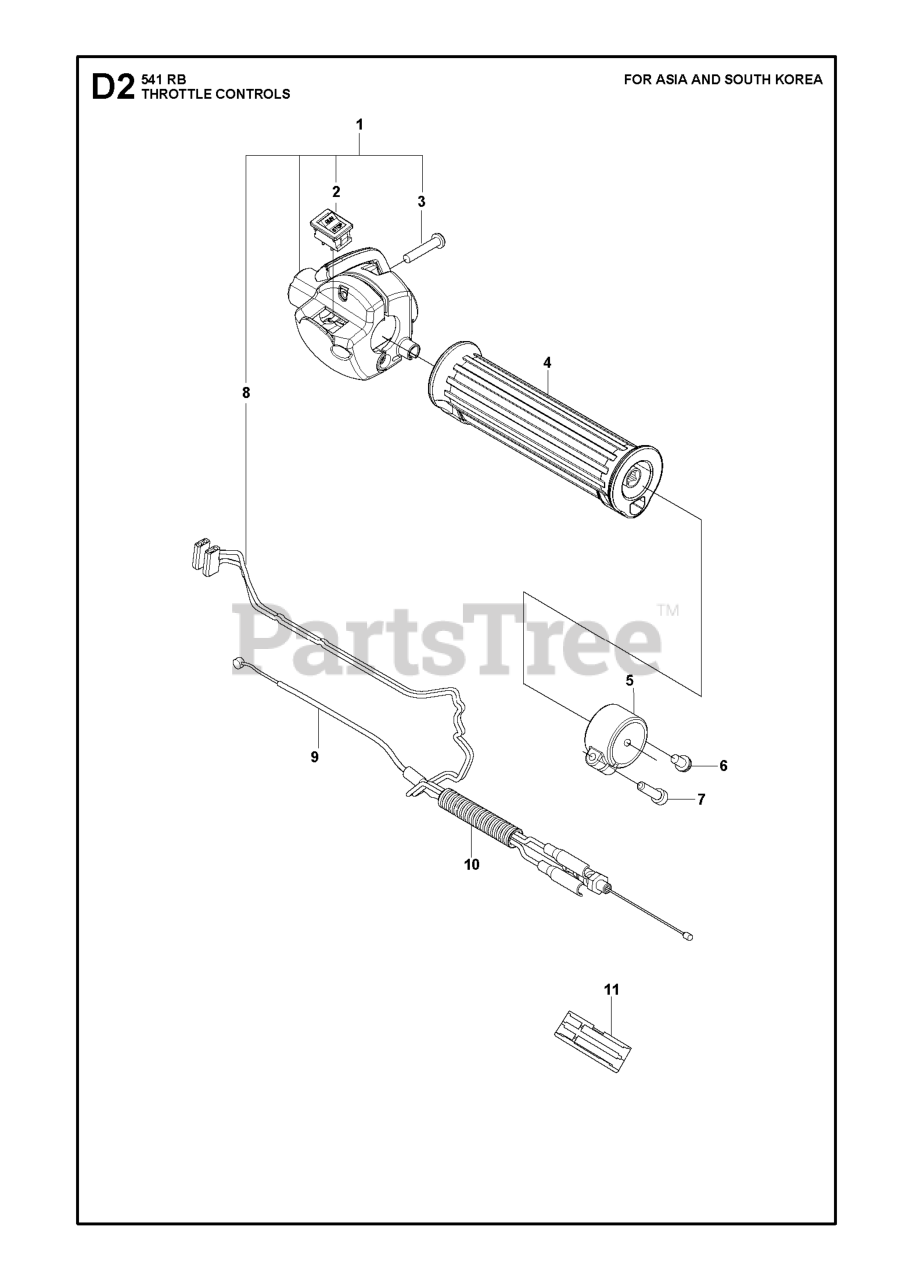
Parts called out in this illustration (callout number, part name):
1	CHOKE CONTROL ASSY
2	STOP SWITCH NM_09091801
2	SWITCH
4	GRIP
5	CLAMP
6	BOLT
7	BOLT TORX
